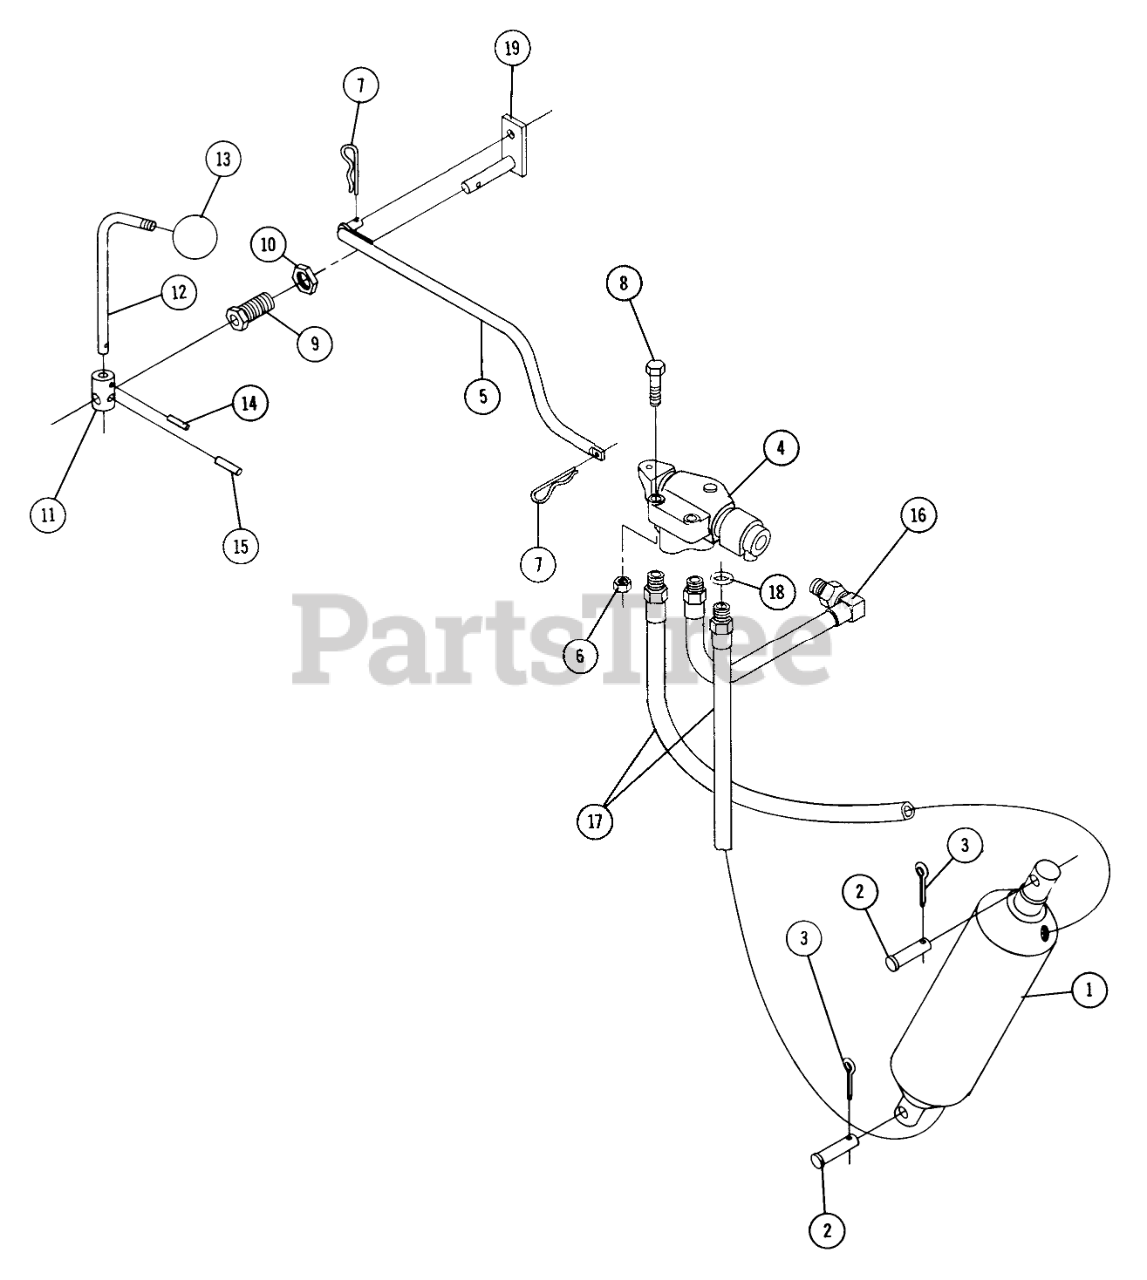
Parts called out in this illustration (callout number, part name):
1	Cylinder
2	PIN CLEVIS .50 DIA
3	Cotter Pin
4	Valve-Hydraulic
5	Link-Rod
6	Nut, 1/4-20
7	Hairpin
8	Bolt 1/4 20 x 1 1/4
9	Sleeve-Spacer
10	Nut 3/1-10 Jam
11	Sleeve-Lever
12	Lever-Hydraulic Valve
13	Knob
14	Pin-Roll
15	PIN-SPIROL
16	Hose-Hydraulic 5 1/4"
17	Hose-Hydraulic 21"
18	O RING
19	Control Rod
